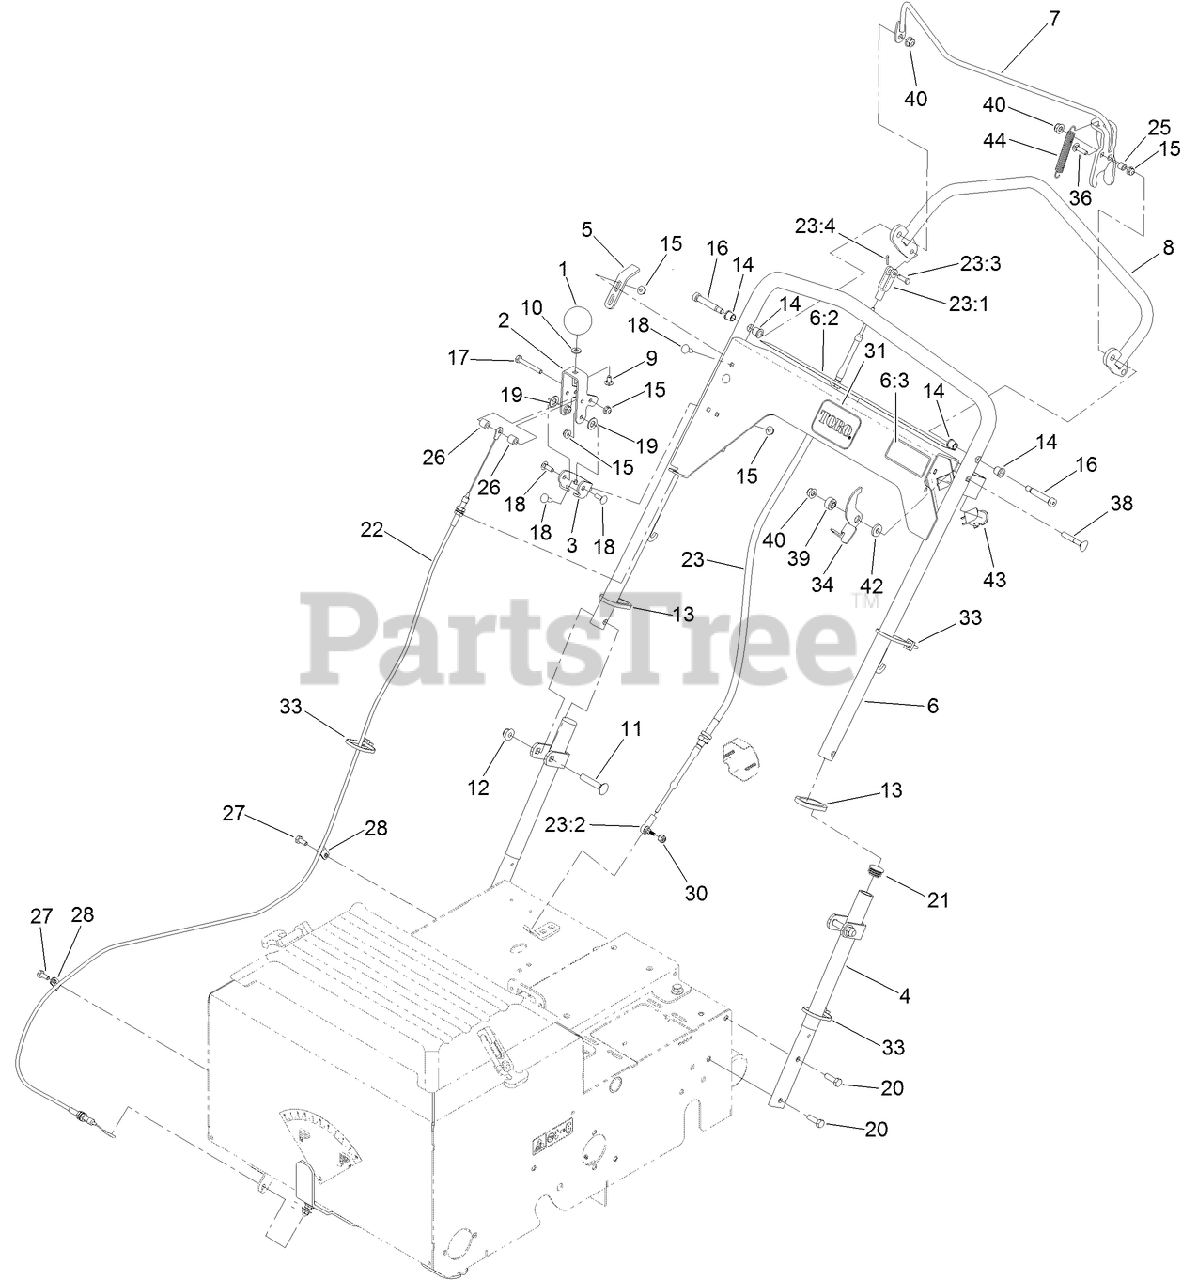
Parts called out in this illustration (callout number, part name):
1	KNOB-RATE, FLOW
2	LEVER-ADJUST, FLOW
3	BRACKET-ADJUST, FLOW
4	HANDLE-LOWER
5	BRACKET-ADJUST, DRIVE
6	HANDLE
6:2	DECAL-CONTROL PANEL, SEEDER
6:3	DECAL-SAFETY LATCH
7	BAIL-CLUTCH
8	HANDLE-DRIVE
9	SCREW-CARR
10	WASHER-FLAT
11	SCREW-CARR
12	NUT-HF, NI
13	RING-HANDLE LOCK
14	BEARING
15	NUT-HF
16	SCREW-SHOULDER
17	SCREW-HH
18	BOLT-CARR
19	WASHER-PLAIN
20	SCREW-HH
22	CABLE-FLOW, SEED
23	CABLE-PUSH PULL
23:1	CLEVIS
23:2	BALL JOINT
23:3	PIN-CLEVIS
23:4	PIN-COTTER
25	SPACER
26	SPACER
27	SCREW-HH
28	CLAMP-R
30	NUT-LOCK
31	DECAL
33	TIE-CABLE
34	LATCH-BAIL
36	SCREW-CARR
39	BUSHING-STEPPED
40	NUT-HF, NI
42	WASHER-FLAT
43	SWITCH-BAIL
44	SPRING
